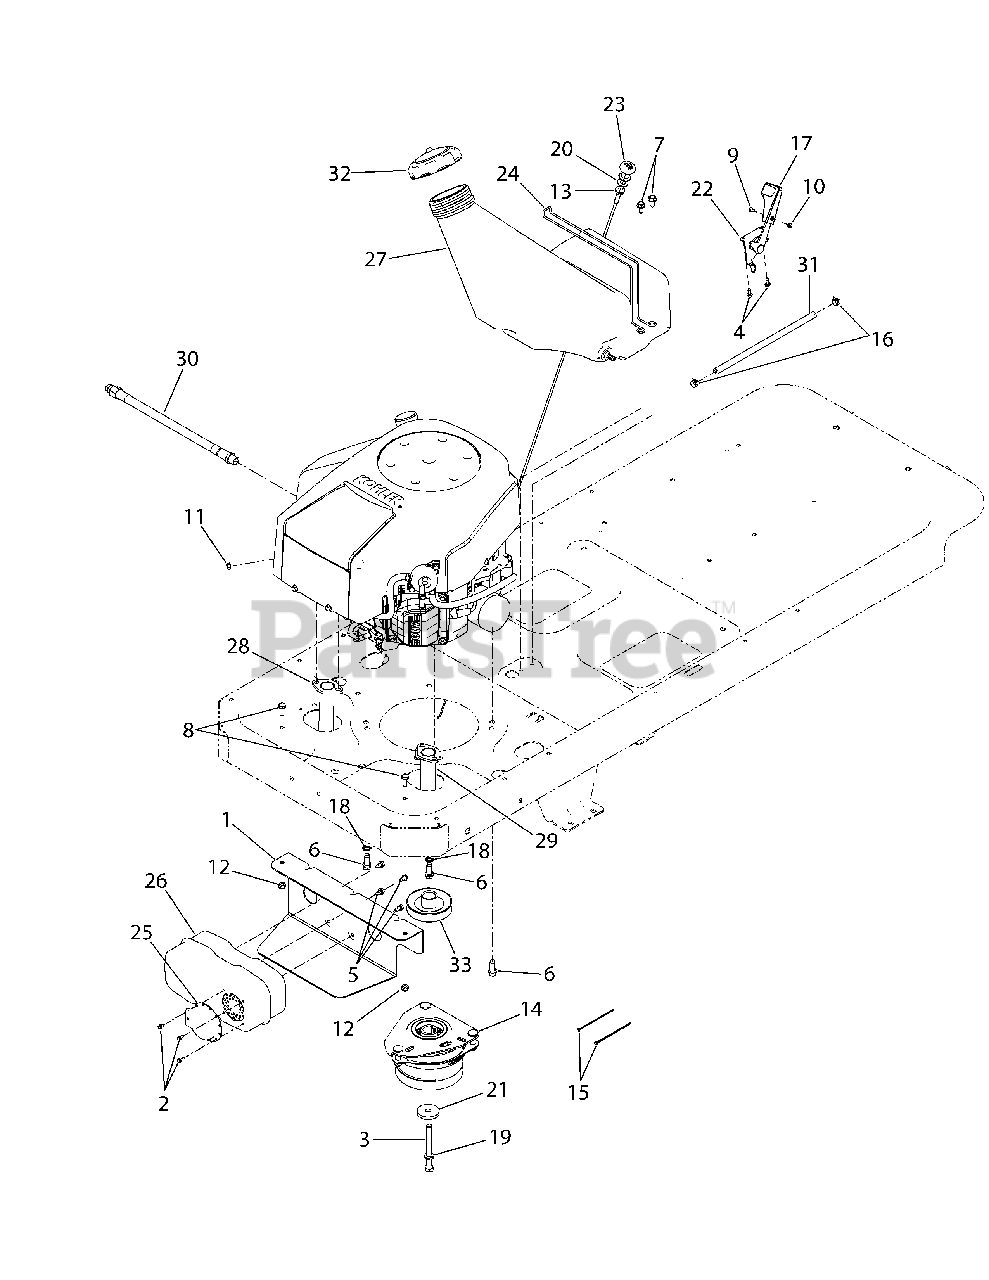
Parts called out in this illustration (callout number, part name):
1	Bracket, Muffler Mounting
2	Screw, Hex Wash. Hd. Tapp #8-18 x .5
3	Screw, Hex Cap, 7/16-20 x 4.0 GR5
4	Screw, Hex Wash. Hd. Tapp #12-16 x .5
5	Screw, Hex Wash. Hd. Tapp 1/4-20 x .5
6	Screw, Hex Wash. Hd. Tapp Sems 3/8-16 x 1.0
7	Screw, Hex Wash. Hd. Tapp 5/16-12 x .75
8	Screw, Hex Cap, 5/16-18 x .75 GR5
9	Screw, Truss Hd. Mach. #8-32 x .375
10	Nut, Hex, #8-32
11	Nut, Hex Sems, 1/4-20 ‘
12	Nut, Hex Insert Lock, 5/16-18 GR5
13	Nut, Hex Jam, 3/8-16 GR2
14	Clutch Assembly, Electric PTO
15	Tie, Clutch Wire
16	Clamp, Hose
17	Knob, Throttle Control
18	Washer, External Tooth Lock, 3/8
19	Washer, Lock, 7/16
20	Washer, Flat, .406 x .875 x .059
21	Washer, Flat, .438 x 1.75 x .25
22	Cable, Throttle, 34.25 Lg
23	Cable, Choke, 61Lg
24	Wire, Tank Mounting
25	Deflector, Muffler
26	Muffler
27	Tank, Fuel, 3.0 Gal.
28	Pipe, Exhaust LH
29	Pipe, Exhaust RH
30	Hose, Oil Drain Extension
31	Hose, Fuel Line
32	Cap, Fuel
33	Pulley, Drive
